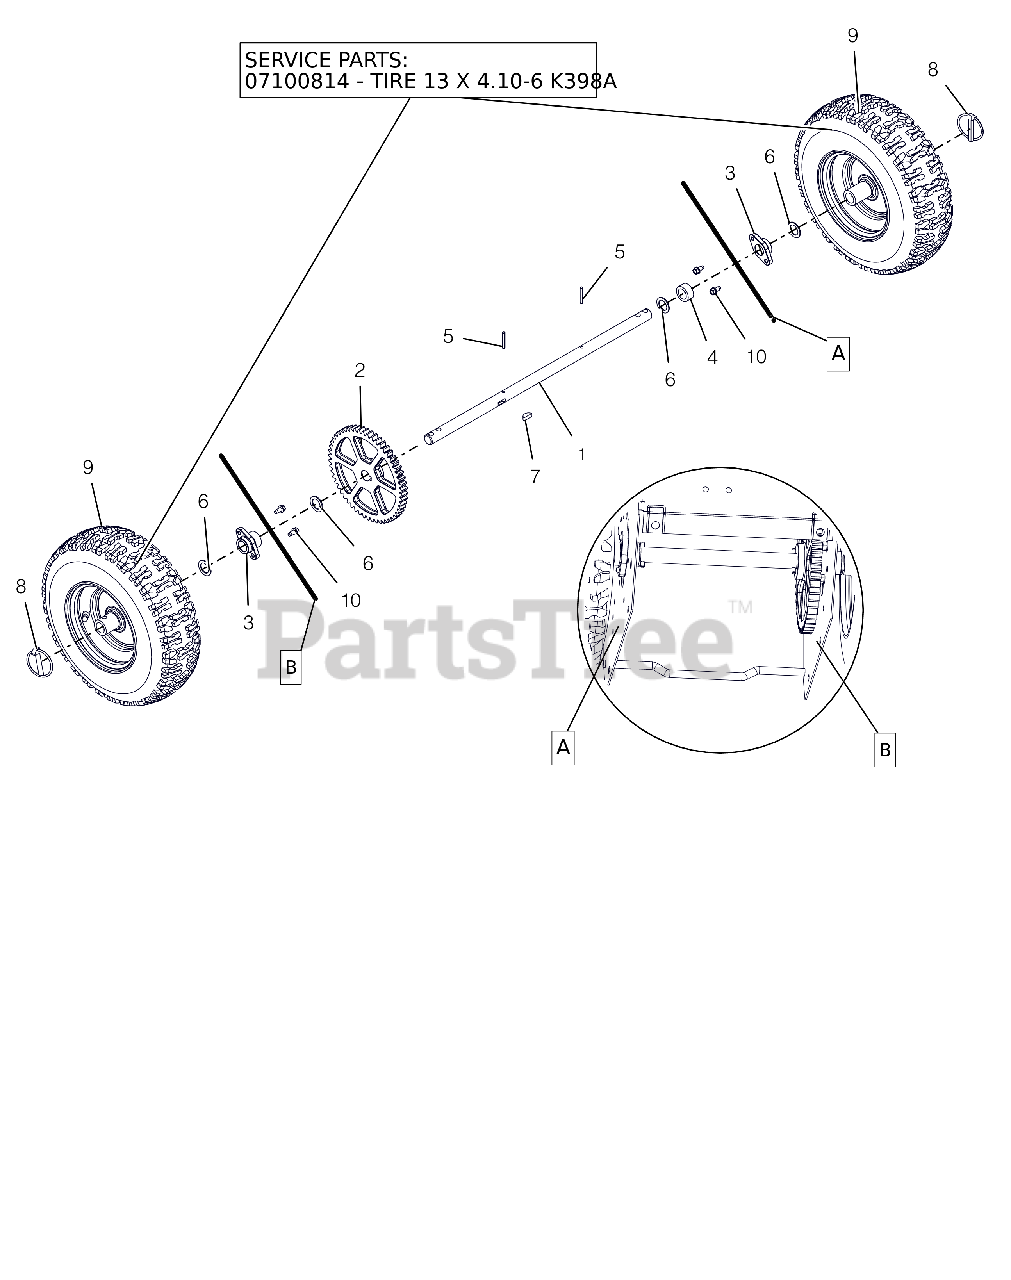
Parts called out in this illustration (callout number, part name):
1	SHAFT, AXLE
2	SPUR GEAR, 54T .75ID X 6.75PD
3	BSHG .75X1.125X.65
4	BSHG-SLV .766 X 1.125 X .500
5	PIN-ROLL .188X1.25
6	WSHR-FL-STL.754X1.125X.062YWZC
7	KEY-WDRF .25X.750X.313 SAE91
8	PIN-LOK .31X1.75
9	TIRE/WHEEL, 13X4.10-6 K398A
9	TIRE, 13" K398A
9	TUBE
10	SCR-TAP .25-20X.50 HWH TR YWZ
